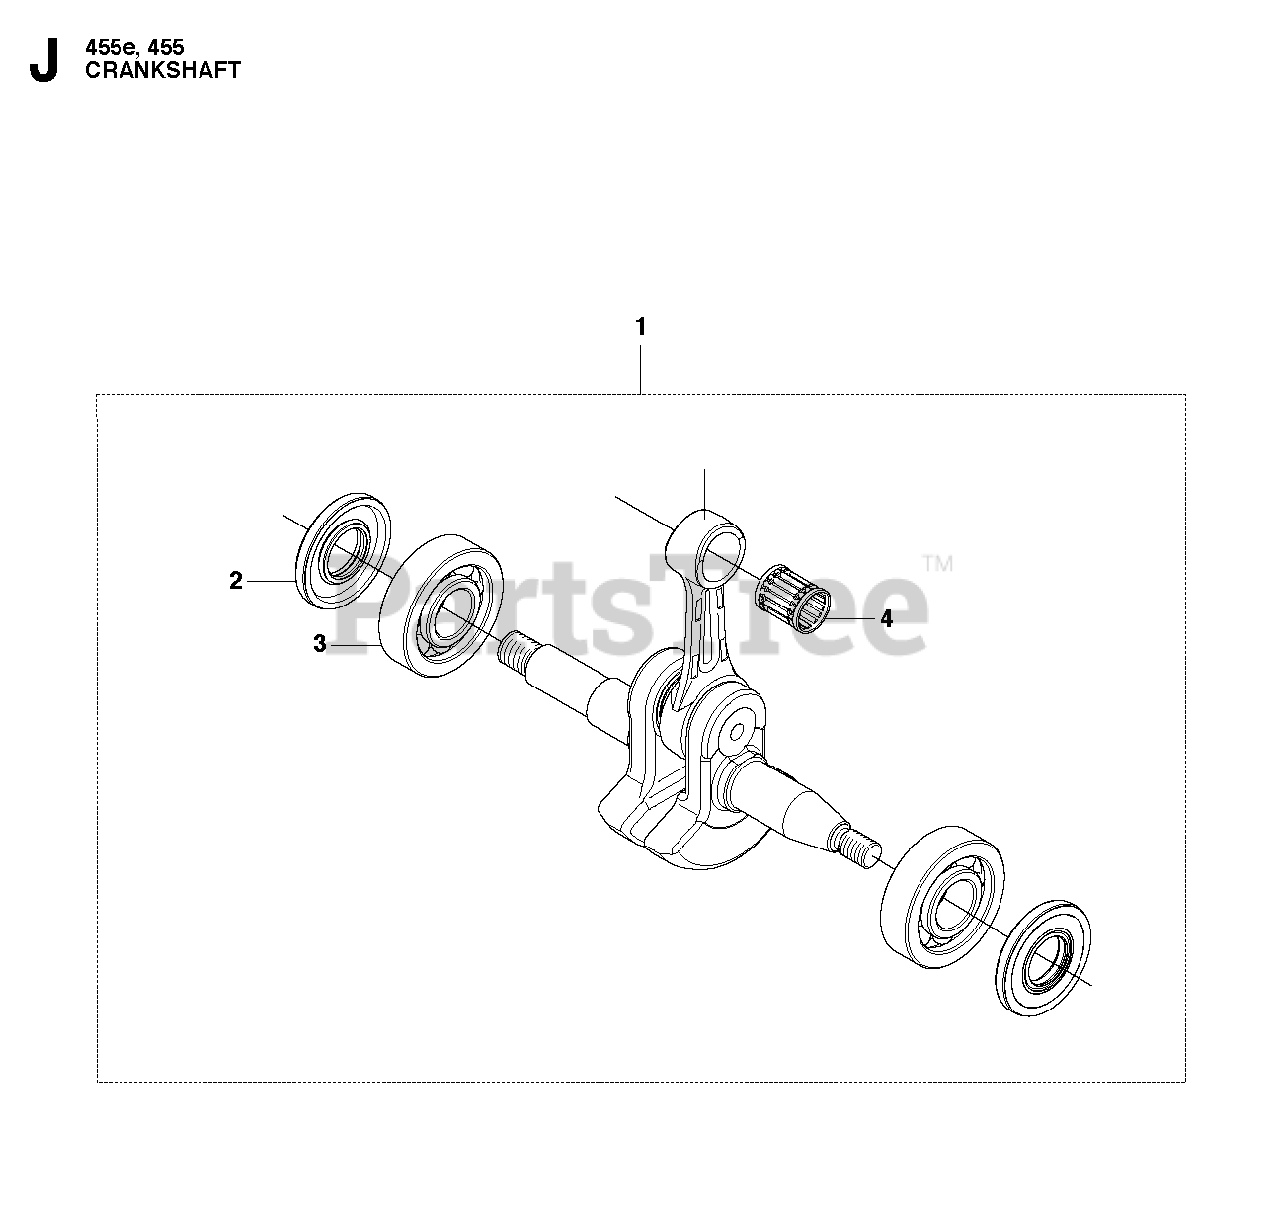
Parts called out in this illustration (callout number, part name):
1	RP CRANKSHAFT CPL
2	SEALING
3	BEARING
4	SUPPORT BUSHING
